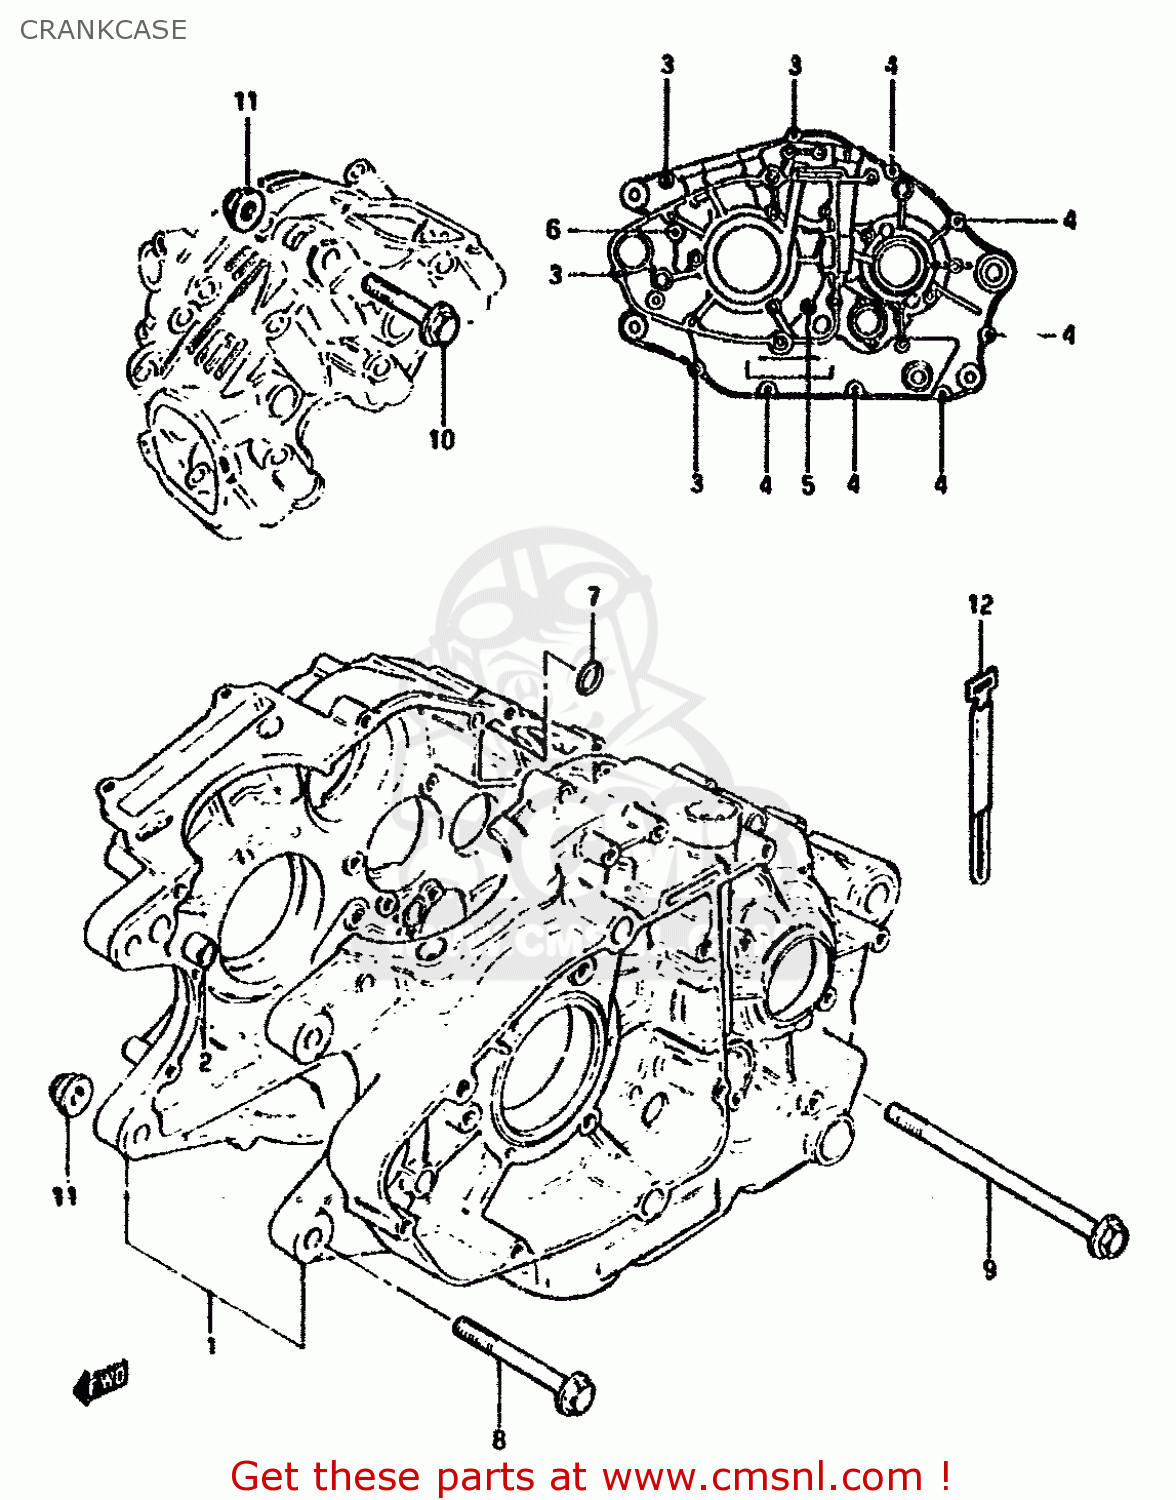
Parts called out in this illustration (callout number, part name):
1	CRANKCASE SET
2	PIN
3	BOLT
4	BOLT
5	BOLT
6	BOLT
7	O RING(D:1.9,ID:8.6)
8	BOLT(8X67)
9	BOLT(8X100)
10	BOLT(8X50)
11	NUT
12	CLAMP,AIR CLEANER DRAIN TUBE
